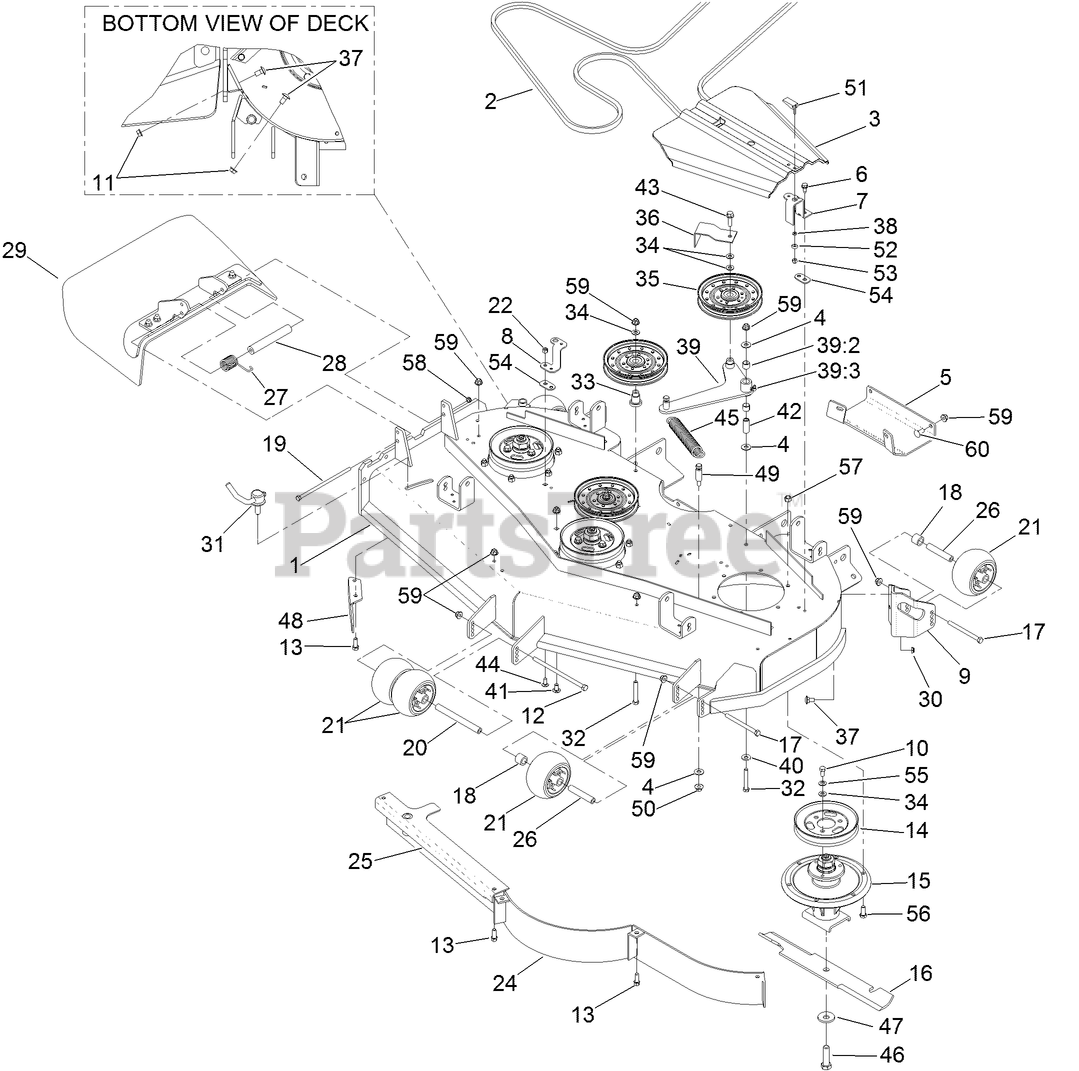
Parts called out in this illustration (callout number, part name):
1	DECK DECAL ASM
2	BELT-V
3	COVER-BELT
4	WASHER-FLAT
5	Plate-Skid
6	SCREW-HWHTF
7	BRACKET-COVER
8	BRACKET-COVER, TALL
9	MOUNT-WHEEL, LH
10	SCREW-HH
11	NUT-HHF, WHIZ
12	SCREW-HH
13	SCREW-HWH
14	Pulley
15	SPINDLE ASM
16	BLADE-18IN, HI FLOW
17	SCREW-HH
18	TUBE-SPACER
19	SCREW-HH
20	SPACER-WHEEL
21	ROLLER-SCALP, ANTI
22	NUT-LOCK, NI
26	TUBE-SPANNER
27	SPRING-TORSION
28	SPACER
29	RUBBER DEFLECTOR ASM
30	NUT-LOCK, NI
31	LEVER ASM
32	SCREW-HH
33	MOUNT-PULLEY
34	WASHER-FLAT
35	IDLER-PULLEY, FLAT
36	GUIDE-BELT
37	SCREW-CARR
38	WASHER
39	DECK IDLER ARM ASM
39:2	SLEEVE-BEARING
39:3	FITTING-GREASE, 90 DEG
40	WASHER-BELLEVILLE
41	SCREW-CARR
42	BUSHING
43	SCREW-HHF
44	SCREW-CARR
45	SPRING-EXTENSION
46	SCREW-BLADE
47	Washer-Blade Bolt, Heavy
48	BAFFLE-DISCHARGE
49	PIN-THREADED, SPRING ANCHOR
50	NUT-HF
51	HANDLE-LATCH, SWELL
52	BUSHING-LATCH, SWELL
53	NUT-LOCK, HH
54	SPACER-BELT COVER
55	WASHER-BELLEVILLE
56	SCREW-HH
57	NUT-LOCK, NI
58	NUT-LOCK, NI
59	NUT-HF, NI
60	SCREW-CARR
